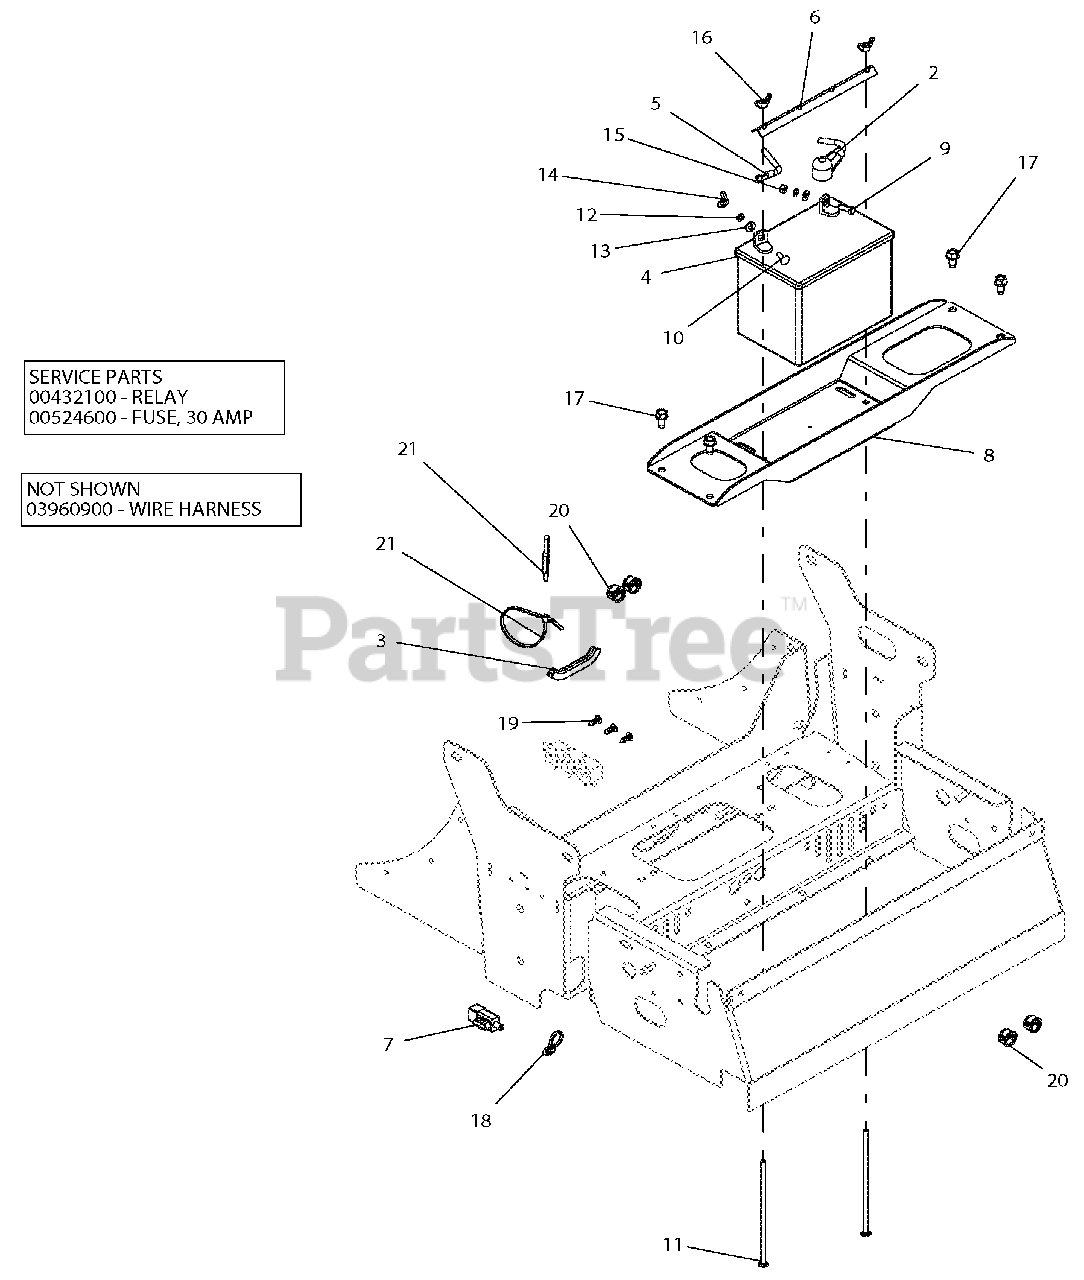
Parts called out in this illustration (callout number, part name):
2	CABLE, POS BATT W/ BOOTS 6 X 35
3	STRIP, COWL - 1.50 LG
4	BATTERY, 300 CCA 10U1L
5	CABLE, NEGATIVE BATTERY 35.00"
6	HOLD DOWN - BLK
7	SWITCH, SNAP IN -N.O./N.O
8	TRAY, BATTERY-RED
9	BLT-HEX .25-20X.75 GR5 YWZC
10	BLT-RDHDSQNK .25-20X.75 G5 YWZC
11	BLT-RDHDSQNK .25-20X7.50 G2 YWZC
12	WSHR-LK .25X.062 REG YWZC
13	WSHR-FL-STL.281X.62X.065 YWZC
14	NUT-WING .250-20 YWZC
15	NUT-HEX .25-20 YWZC
16	NUT-LOCKING WING 1/4-20
17	SCR-TAP .38-16X.75 HWH TR YWZ
18	CABLE TIE W/ TREE (.25 HOLE)
19	RIVET, .25 NYLON PANEL
20	BUSH, PANEL SNAP .687X.875X.56
21	CABLE, TIE 5.50 LG
